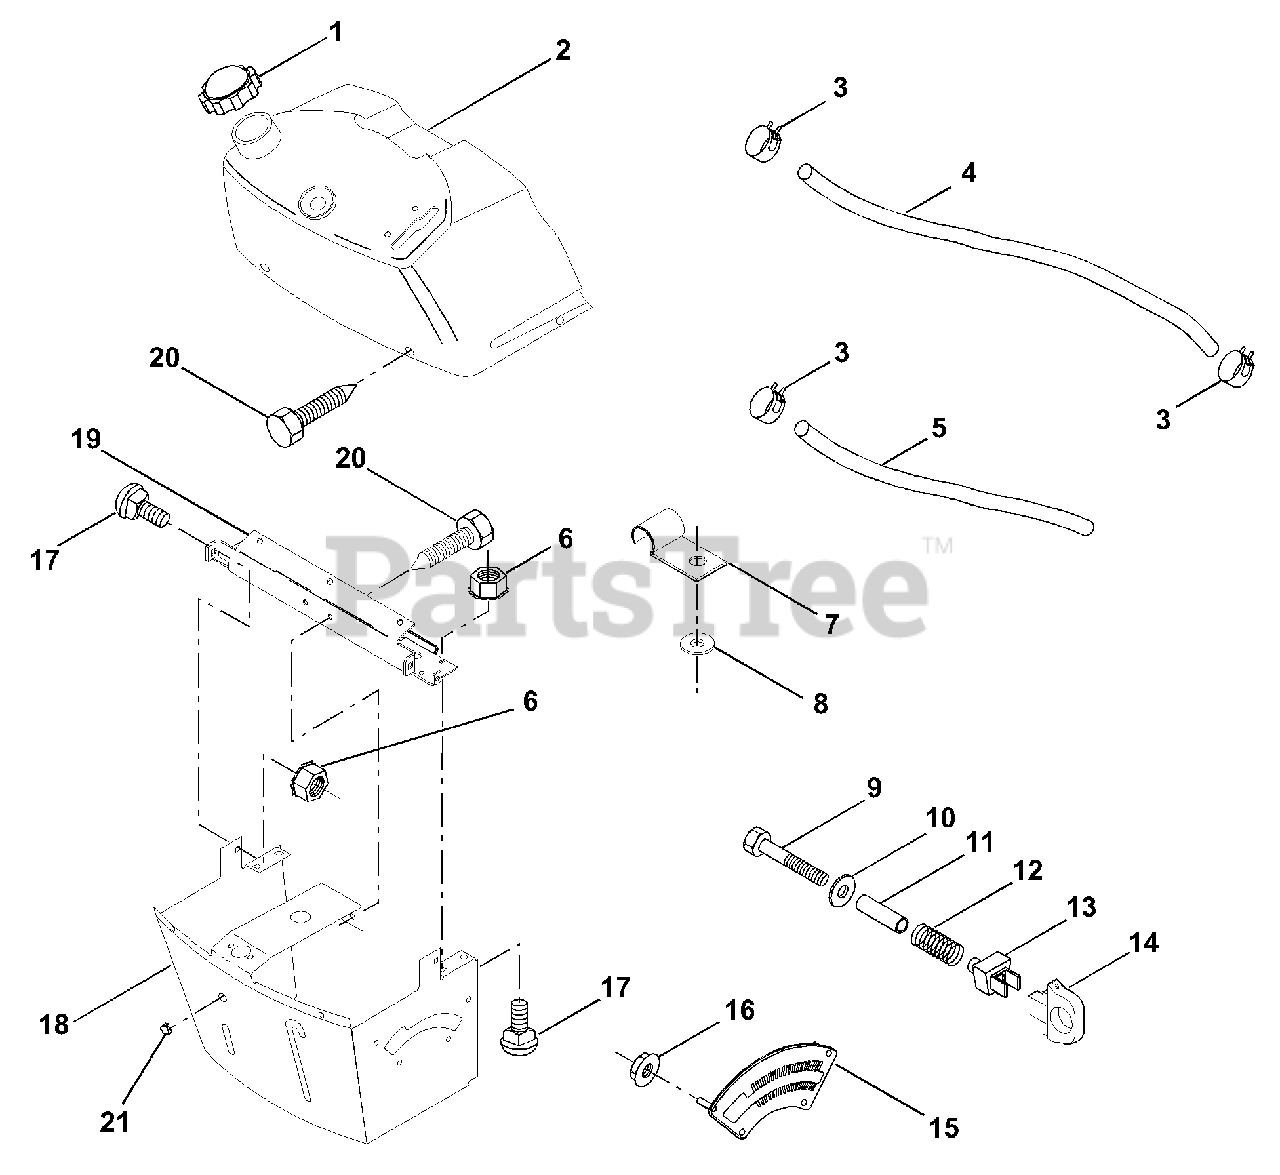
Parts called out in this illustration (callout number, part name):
2	Assembly, Dash & Fuel Tank
3	Clamp, Hose
4	Line, Fuel
5	Line, Fuel
6	Nut, Hex, Keps 1/4-20
7	Clip, Fuel Line
8	Washer 9/32 x 3/4 x 16 Ga.
9	Bolt, Hex, Fin 1/4-20 x 1-3/4
10	Washer 11/32 x 11/16 x 16 Ga.
11	Spacer, Split
13	Clip, Height Adjustment
14	Knob, Height Stop
15	Adjustment, Quadrant Height
16	Nut, Self-Threading 3/16-18
17	Bolt, Carriage 1/4-20 x 1/2 Gr. 5
18	Support Assembly, Dash
19	Brace, Cross
20	Screw, Self-Tapping 1/4-20 x 1/2
21	Plug Dome Black
